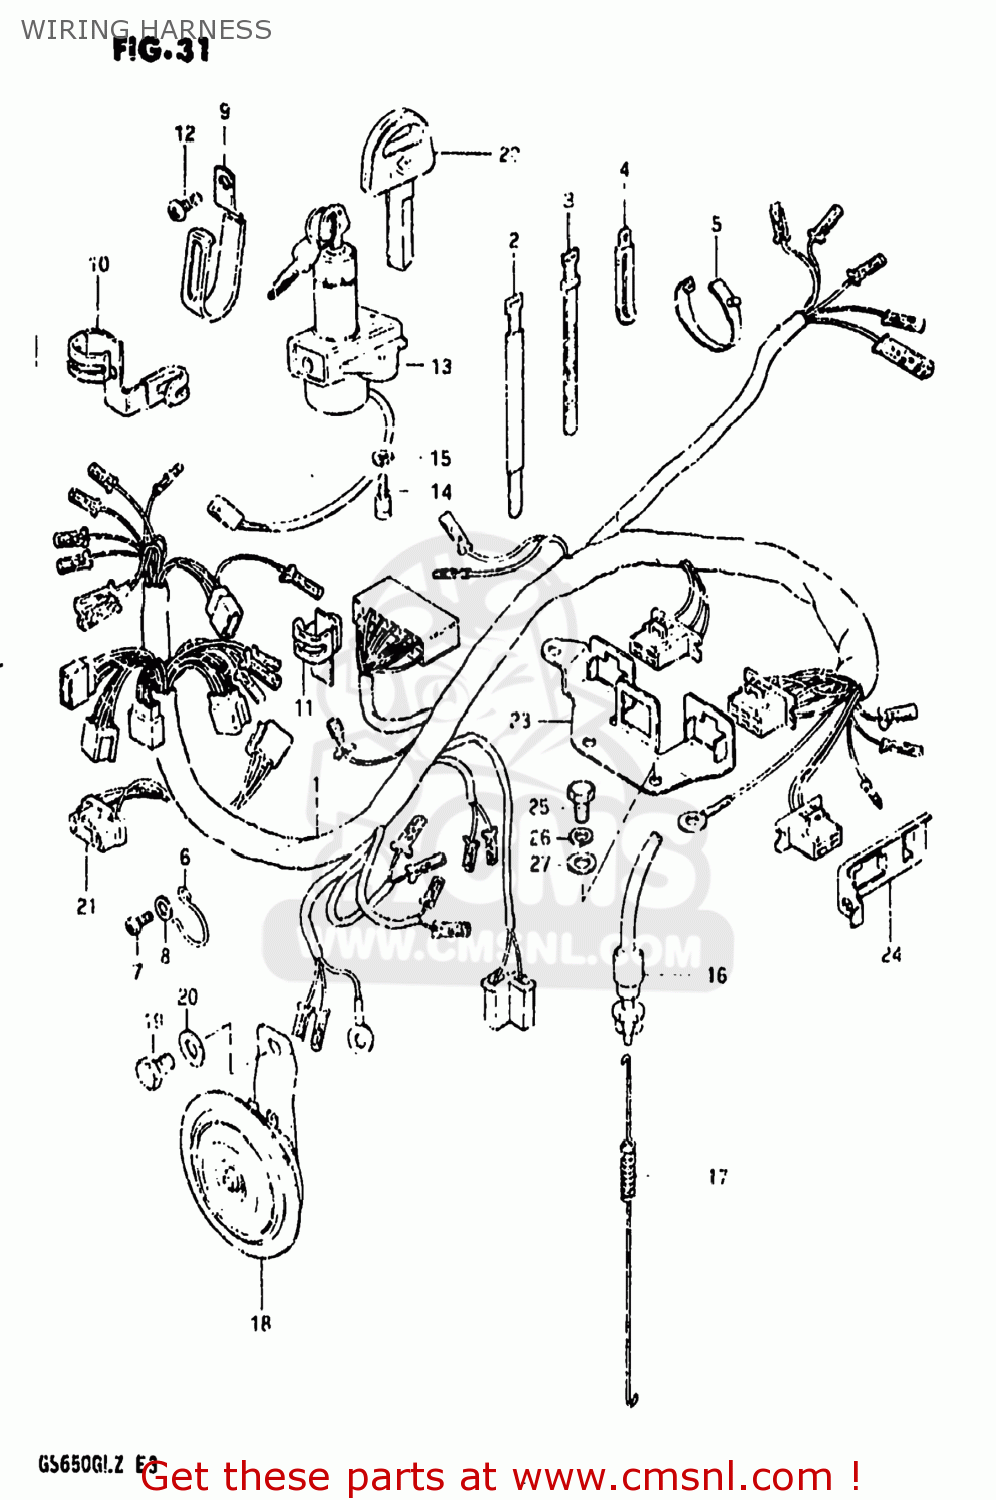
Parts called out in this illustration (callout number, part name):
1	HARNESS,WIRING
2	CLAMP(L:250)
3	CLAMP
4	CLAMP
5	CLAMP,L:88
6	GUIDE,WIRING HARNESS
7	SCREW 6X12
8	WASHER
9	CLAMP,WIRING HARNESS
10	CLAMP,WIRING HARNESS
11	CLAMP,WIRING HARNESS
12	SCREW
13	SWITCH ASSY,IGNITION
14	BOLT
15	LOCK WASHER
16	SWITCH ASSEMBLY,STOP LAMP
17	SPRING
18	HORN MODEL Z
19	BOLT 8X12
20	WASHER
21	LEAD WIRE,HEADLAMP
22	KEY,BLANK
23	PLATE, COUPLER HOLDER (A)
24	PLATE, COUPLER HOLDER (B)
25	BOLT
26	LOCK WASHER
27	WASHER
